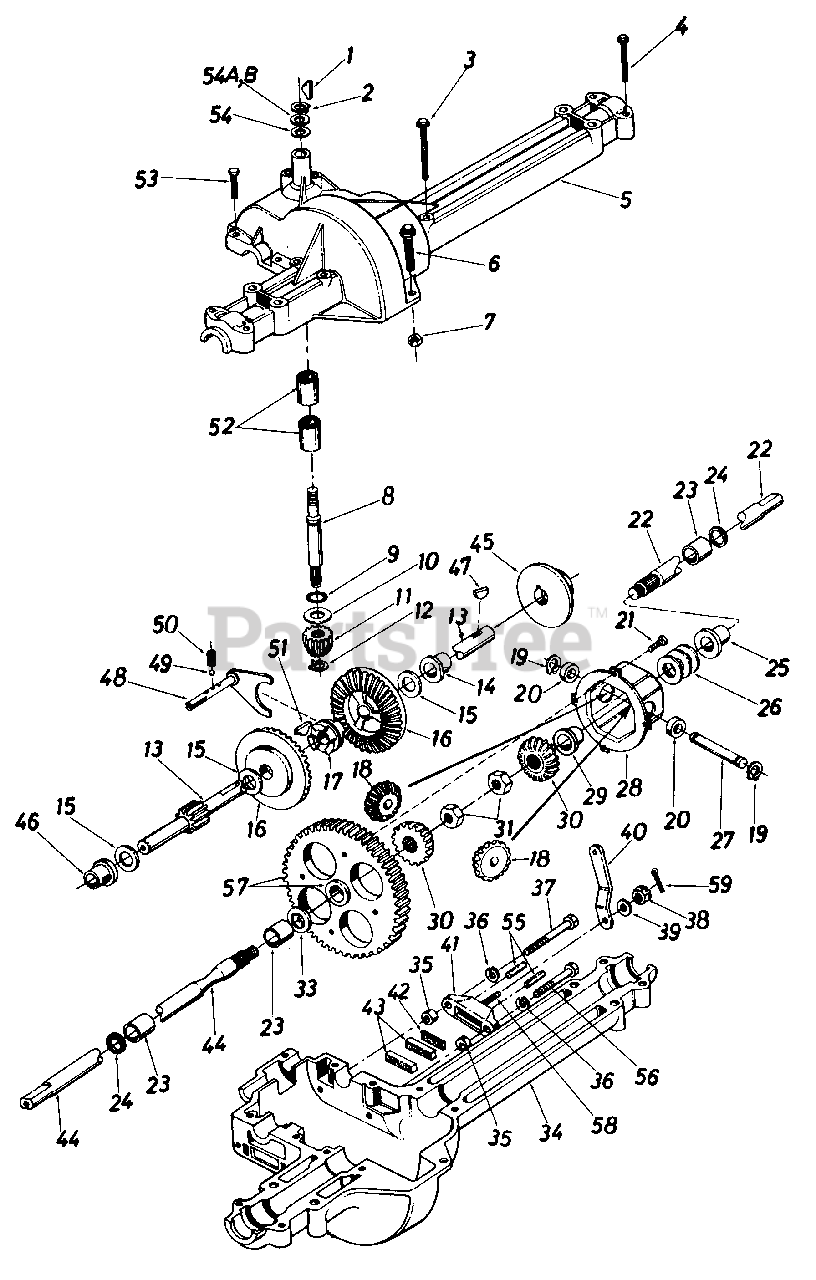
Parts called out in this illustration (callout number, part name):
1	#4 Hi-Pro Key 3/32 x 518" Dia.
2	Snap Ring .625" Shaft
3	Hex Bolt 1/4-20 x 1.75" Lg.
4	Hex Bolt 1/4-20 x 1.25" Lg.
5	Upper Housing
6	Hex Fl-Bolt 1/4-20 x .75" Lg.
7	Hex Nut 1/4-20 Thd.
8	Input Shaft
9	Square Seal 5/8" I.D.
10	Thrust Washer 518" I.D. x 1.25" O.D.
11	Pinion Input 14T
12	Retaining Ring 7/16" Ext.
13	Drive Shaft R.H.
14	Flange Brg. 5/8" I.D. x 3/4" Lg.
15	Fl-Wash.
16	Bevel Gear 42T
17	Clutch Collar
18	Miter Gear 15T
19	Snap Ring
20	Thrust Bearing 1/2" I.D. x 1.0" O.D.
21	Pan Head Scr. 1/4-20 x .50" Lg. w/Patch
22	Axle R.H.
23	Sleeve Bearing 3/4" I.D. x 1.0" Lg.
24	Oil Seal 3/4" I.D.
25	Flange Bearing 3/4" I.D. x 15/16" Lg.
26	Fl-Wash. .760" I.D. x 1.49" O.D.
27	Cross Shaft
28	Differential Housing Ass'y.
30	Miter Gear
31	Hex Ins. L-Nut 1/2-20 Thd.
33	Fl-Wash. 75" I.D. x 1.5" O.D.
34	Lower Housing
35	Spacer .53" O.D. x 3/8" Lg.
36	L-Wash. 1/4" I.D.
37	Hex Bolt 1/4-20 x 1.50" Lg. (Grade 5)
38	Castle Nut 5/16-24 Thd.
39	Fl-Wash. 34" I.D. x .875" O.D.
40	Actuating Arm R.H.
41	Brake Yoke
42	Puck Plate
43	Brake Puck
44	Axle L.H.
45	Brake Disc
46	Flange Bearing 5/8" I.D. x 15/16" Lg.
47	Woodruff Key 3/16 x 5/8 HT
48	Shift Fork Ass'y.
49	Ball Detent .250" Dia.
50	Spring Detent
51	#9 Hi-Pro Key 3/16" x 3/4" Dia. HT
52	Needle Brg. 5/8" I.D. x 1/2" Lg.
53	Hex Bolt 1/4-20 x 1.00" Lg.
54	Fl-Wash. 5/8" I.D. x .030
54A	Fl-Wash. 5/8" I.D. x .040
54B	Fl-Wash. 5/8" I.D. x .020
55	Actuating Pin 5/16" Dia.
56	Hex Bolt 1/4-20 x 1.50" Lg. (Grade 5)
57	Differential Gear 72T Ass'y. w/Bearing
58	Sq. Hd. Bolt 5/16-24 Thd.
59	Cotter Pin 3/32" Dia. x 50" Lg.
